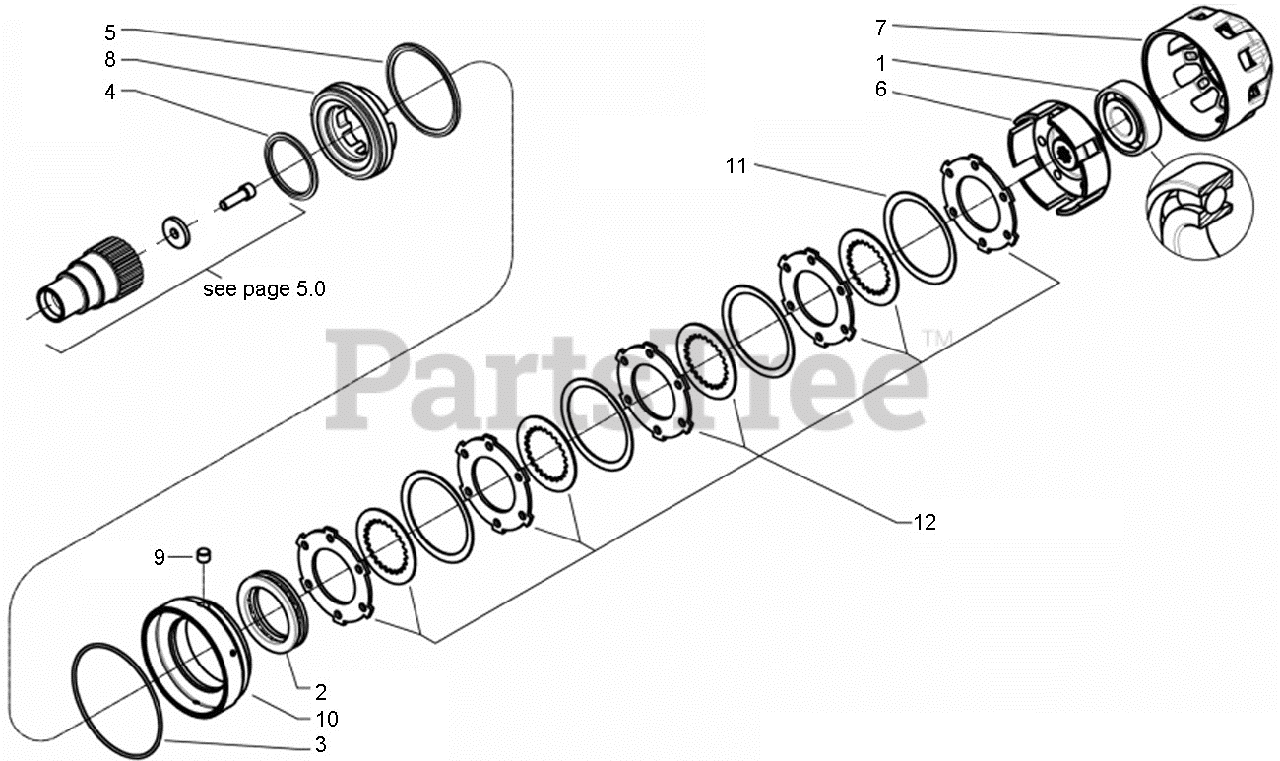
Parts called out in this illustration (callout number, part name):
1	BEARING
2	BEARING
3	O-RING
6	CLUTCH, BASKET
8	PISTON
11	SPRING
12	FRICTION DISK KIT
